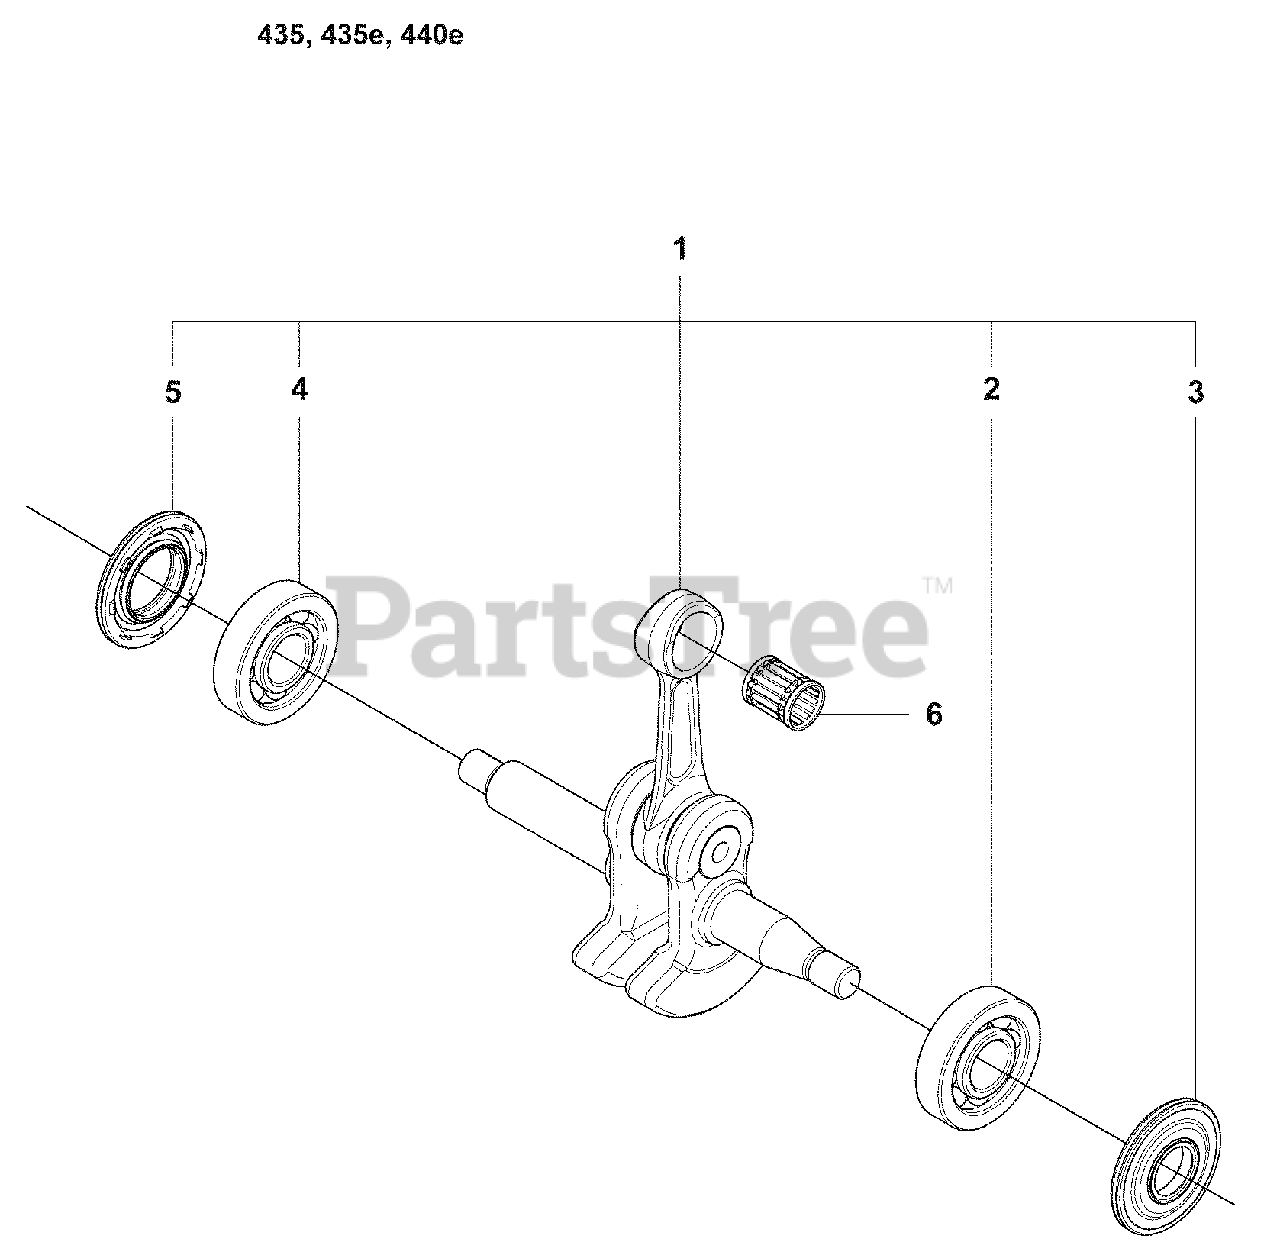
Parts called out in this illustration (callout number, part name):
1	Crankshaft and Gear Assembly
2	Ball Bearing, 6001 OD32
3	Sealing
4	Ball Bearing, 6001 OD32W
5	Sealing
6	Support Bushing
